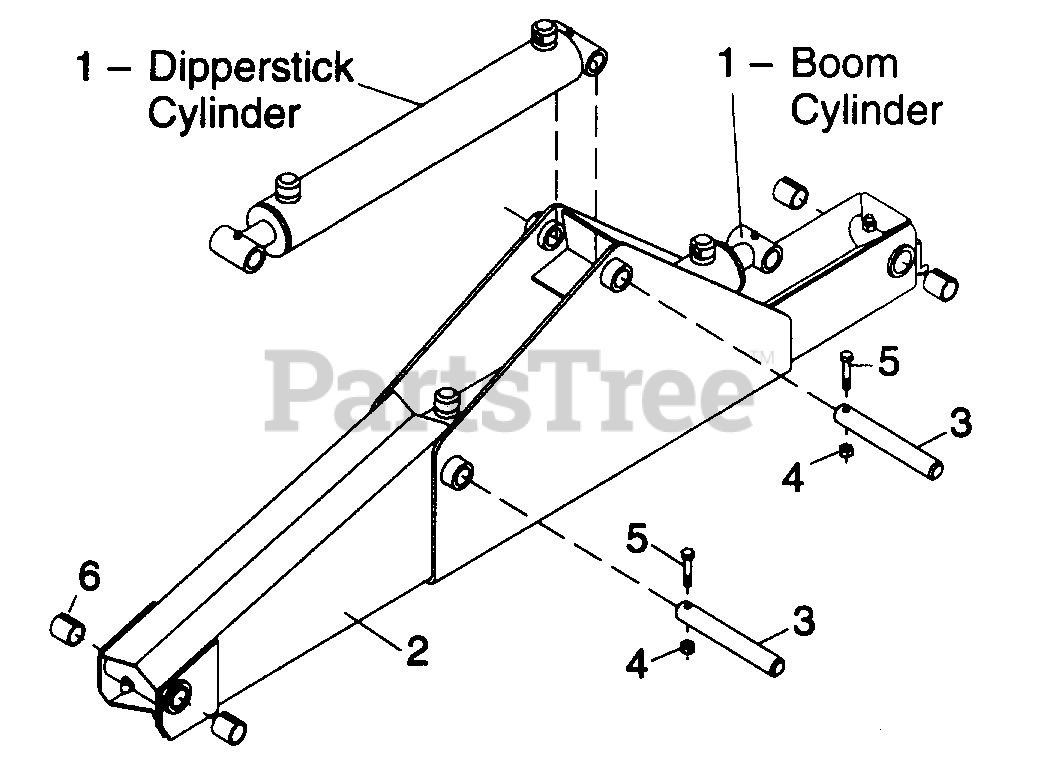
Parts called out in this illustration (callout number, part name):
1	2.50 x 16.75 Double acting hydraulic cylinder K
3	1.00 x 5.92 x 6.31 Drilled bar
4	1/4 NC Hex locknut
5	1/4 NC x 2-1/4 Hex head cap screw GR5
6	1 x 1-1/4 x 1-1/2 Tension bushing
